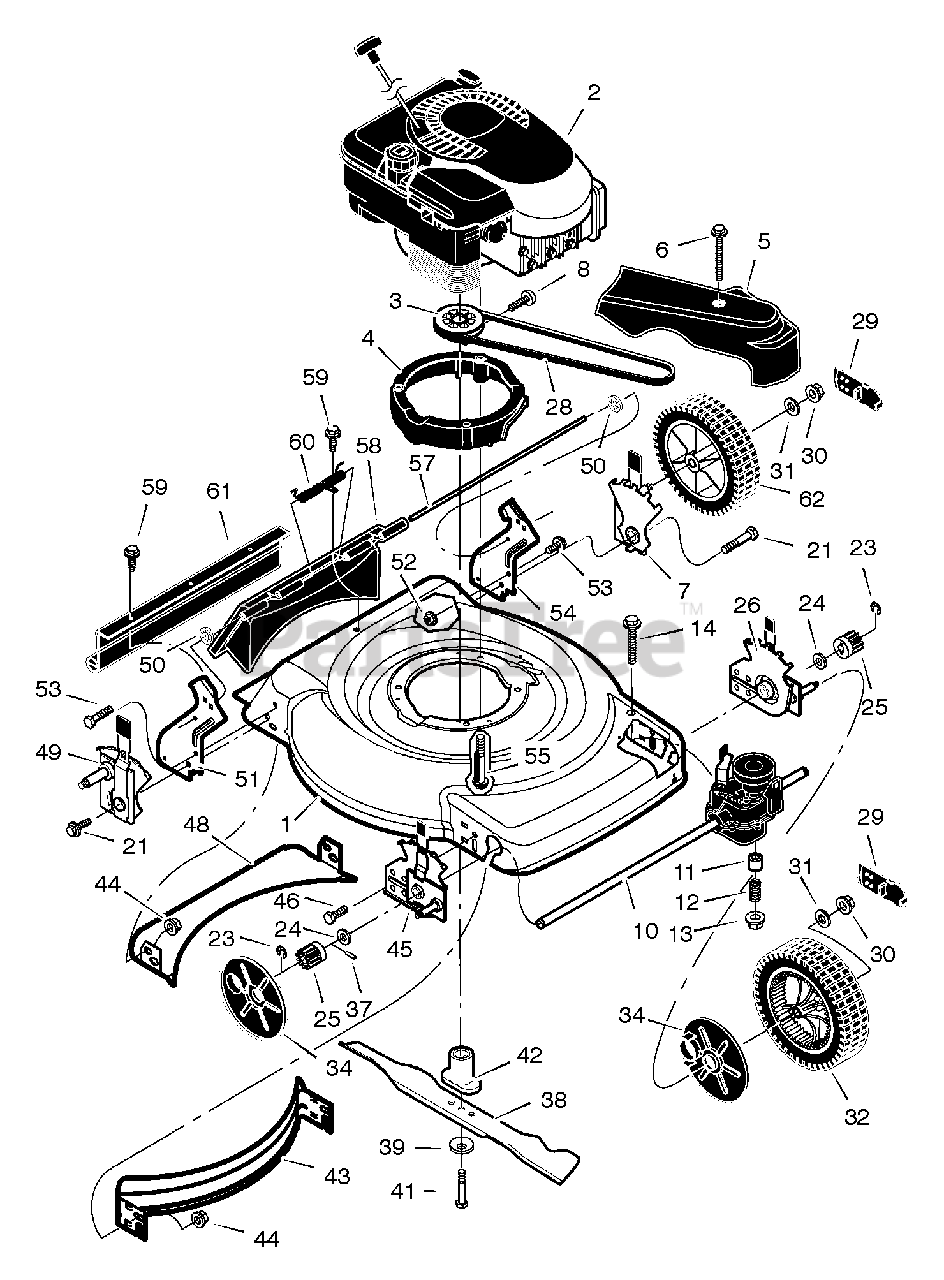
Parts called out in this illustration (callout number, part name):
1	Housing
2	Engine *
3	Pulley, Drive
4	Spacer, Engine
5	Cover, Belt (Black)
6	Screw
7	Adjuster, Left Rear Height
8	Screw
10	Transmission *
12	Spring, Compression
13	Nut
14	Bolt
21	Bolt
25	Gear, Pinion
26	Adjuster, Left Front Height
29	Cap, Hub
30	Nut, Flange
31	Washer
32	Wheel & Tire, Front
34	Cover, Dust
37	Pin, Drive
38	Blade
39	Washer, Belleville
42	Adapter, Blade
43	Baffle, Front
44	Nut, Flange
45	Adjuster, Right Front Height
46	Bolt
48	Baffle, Rear
49	Adjuster, Right Rear Height
50	Retainer, Push
51	Bracket, Right Handle
52	Nut, Flange
53	Bolt
54	Bracket, Left Handle
55	Bolt, Engine
57	Rod, Pivot
58	Door, Rear (Black)
60	Spring
61	Guard, Rear
62	Wheel & Tire, Rear
